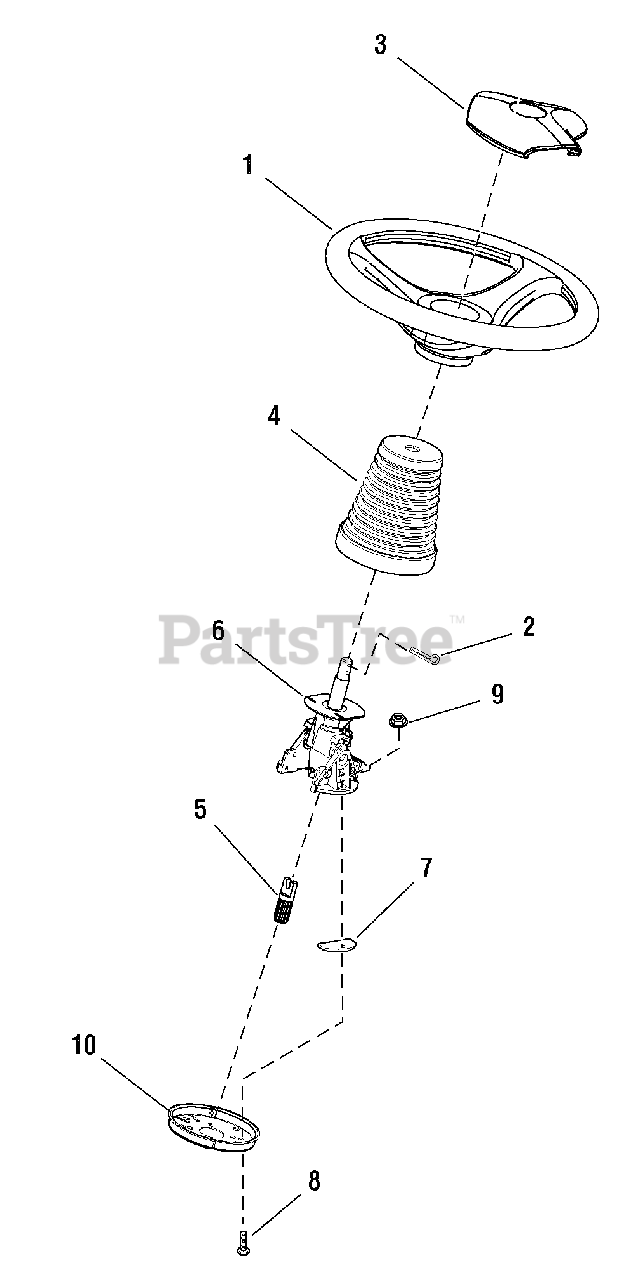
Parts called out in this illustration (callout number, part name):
1	STEERING WHEEL
3	CAP, Steering Wheel, Simplicity
4	BELLOWS
5	ADAPTER, Tilt Steering
6	TILT STEERING
7	SPACER, Flat
8	CAPSCREW, 5/16-18 x 1
9	NUT, Hex Keps, 5/16-18
10	MOUNTING PLATE, Steering
